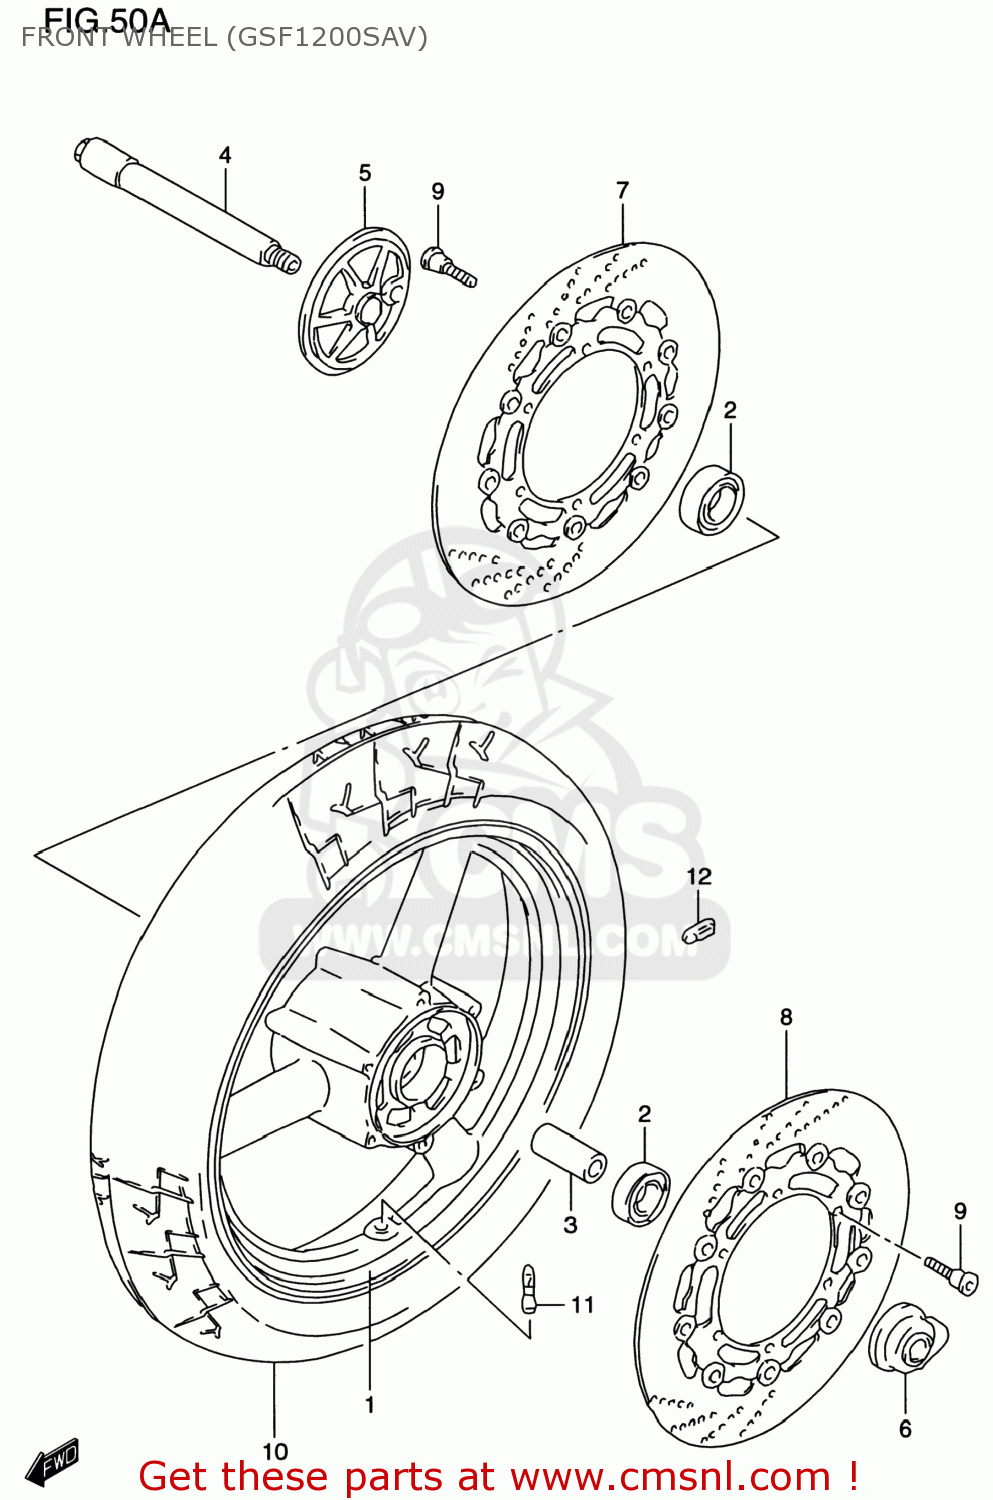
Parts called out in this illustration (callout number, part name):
1	WHEEL SET,FRONT (17XMT3)
2	BEARING
3	SPACER(20.8X27.2X74)
4	AXLE,FR
5	PANEL,SPEED SENSOR FR
6	BOX ASSY,SPEEDOMETER GEAR
7	DISC,FR BRAKE,R
8	DISC,FR BRAKE,L
9	BOLT 8X33
10	TIRE,FRONT 120/70 ZR17
11	VALVE ASSY,WHEEL RIM(TR412)
12	BALANCER,WHEEL (10G)
